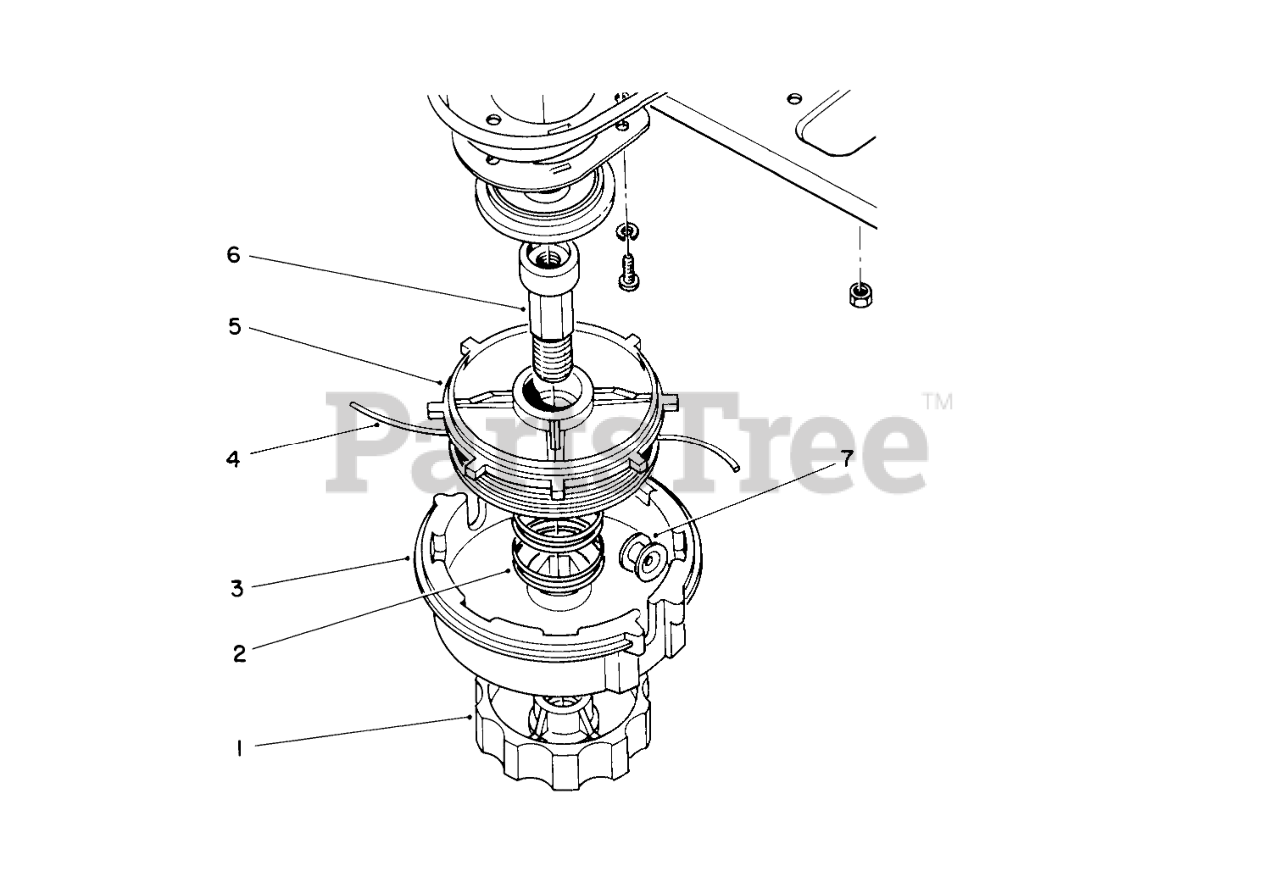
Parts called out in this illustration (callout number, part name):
1	LH KNOB(SERVICE ONLY)
2	SPRING (SERVICE)
3	SPOOL HSG (SERVICE ONLY
5	INNER SPOOL(SERV ONLY)
6	SHAFT (SERVICE ONLY)
7	EYELET(SERVICE)
